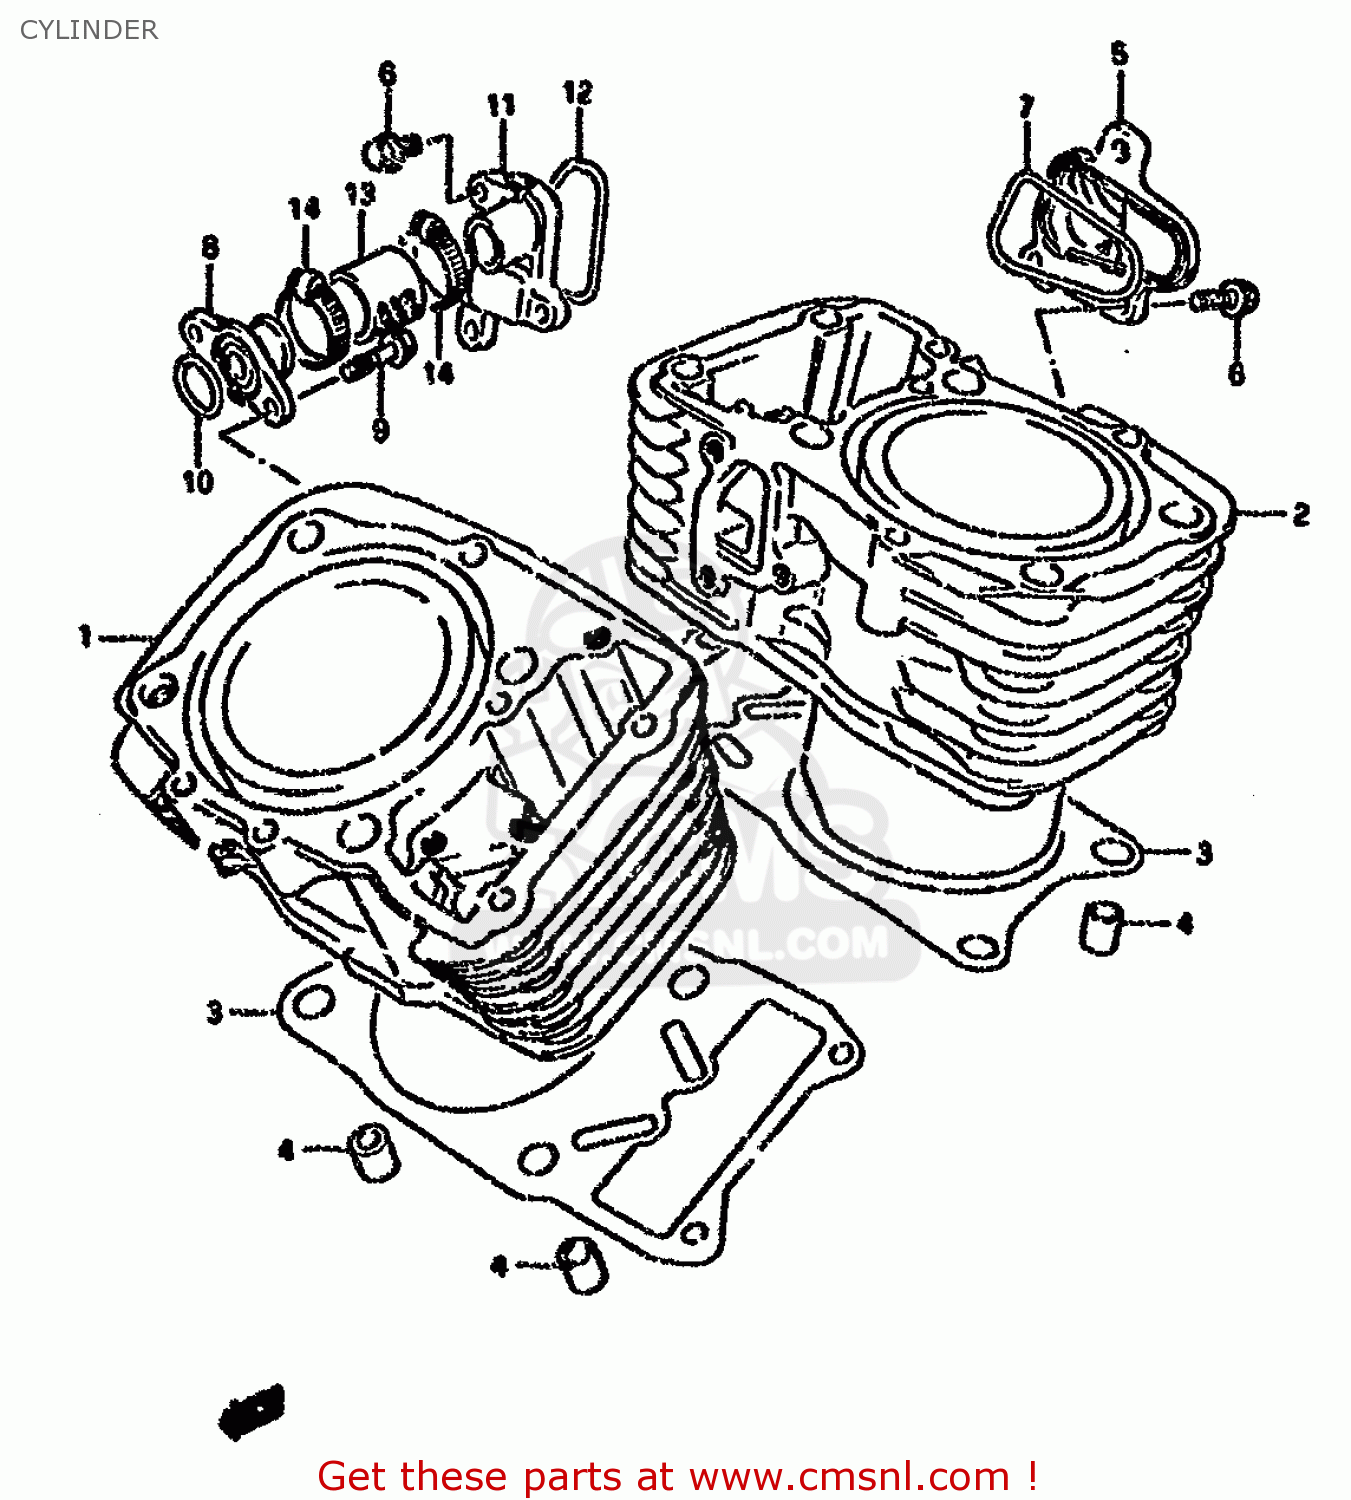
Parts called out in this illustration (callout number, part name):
1	CYLINDER,FRONT
2	CYLINDER,RR
3	GASKET,CYLINDER
4	PIN
5	CHAMBER,WATER,INLET
6	BOLT
7	O RING,INLET WATER CHAMBER
8	UNION,WATER INLET
9	BOLT
10	O RING(D:2.4,ID:15.8)
11	CHAMBER,WATER OUTLET
12	O RING,OUTLET WATER CHAMBER
13	HOSE,RADIATOR JOINT NO.1
14	CLAMP
